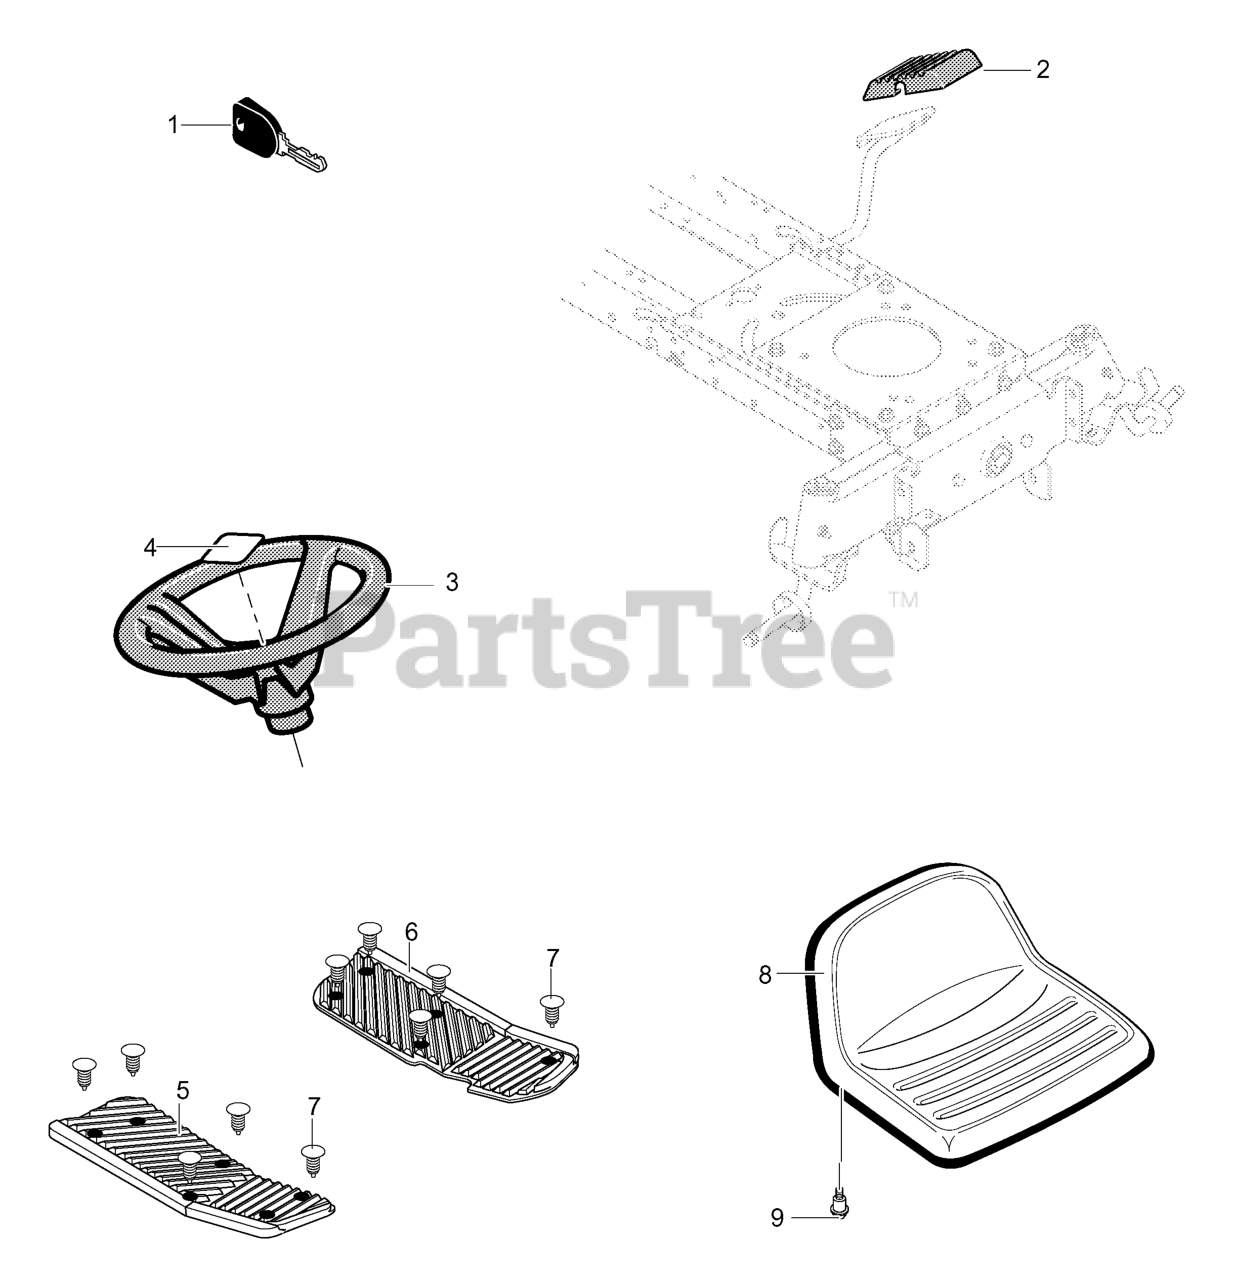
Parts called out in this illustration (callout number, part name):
1	Ignition Key
2	Pad, Clutch/Brake
3	Steering Wheel
4	Insert, 4-Spoke
5	Footrest Pad RH
6	Footrest Pad LH
7	Ratchet Fastener
9	Shoulder Bolt 5/16-18
